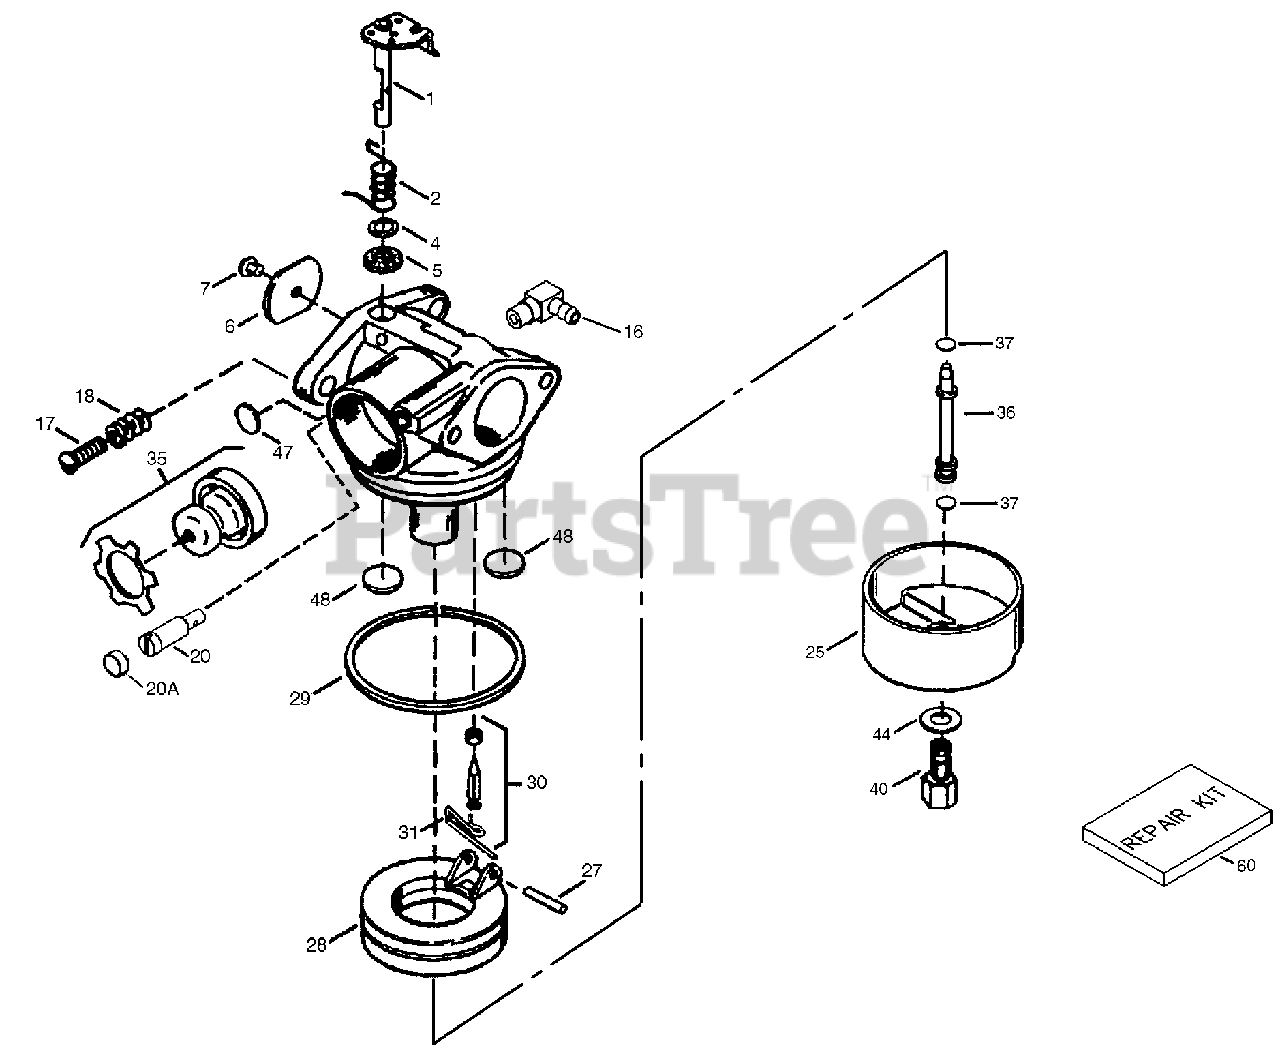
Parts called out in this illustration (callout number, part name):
1	Throttle Shaft & LeverAssembly
2	Throttle Return Spring
4	Dust Seal Washer
5	Dust Seal (Throttle)
6	Throttle Shutter
7	Shutter Screw
16	Fuel Fitting
17	Throttle Crack
18	Tension Spring
20	Idle Restrictor Screw
20A	Idle Restrictor Screw
25	Float Bowl
27	Float Shaft
28	Float
29	Float Bowl "O" Ring
30	Inlet Needle, Seat,& Clip (Incl. 31)
31	Spring Clip
35	Primer Bulb/RetainerRing
36	Main Nozzle Tube
37	O-Ring, Main NozzleTube
40	High Speed Bowl Nut
44	Bowl Nut Washer
47	Welch Plug, Idle
48	Welch Plug,Atmospheric Vent
60	Repair Kit
